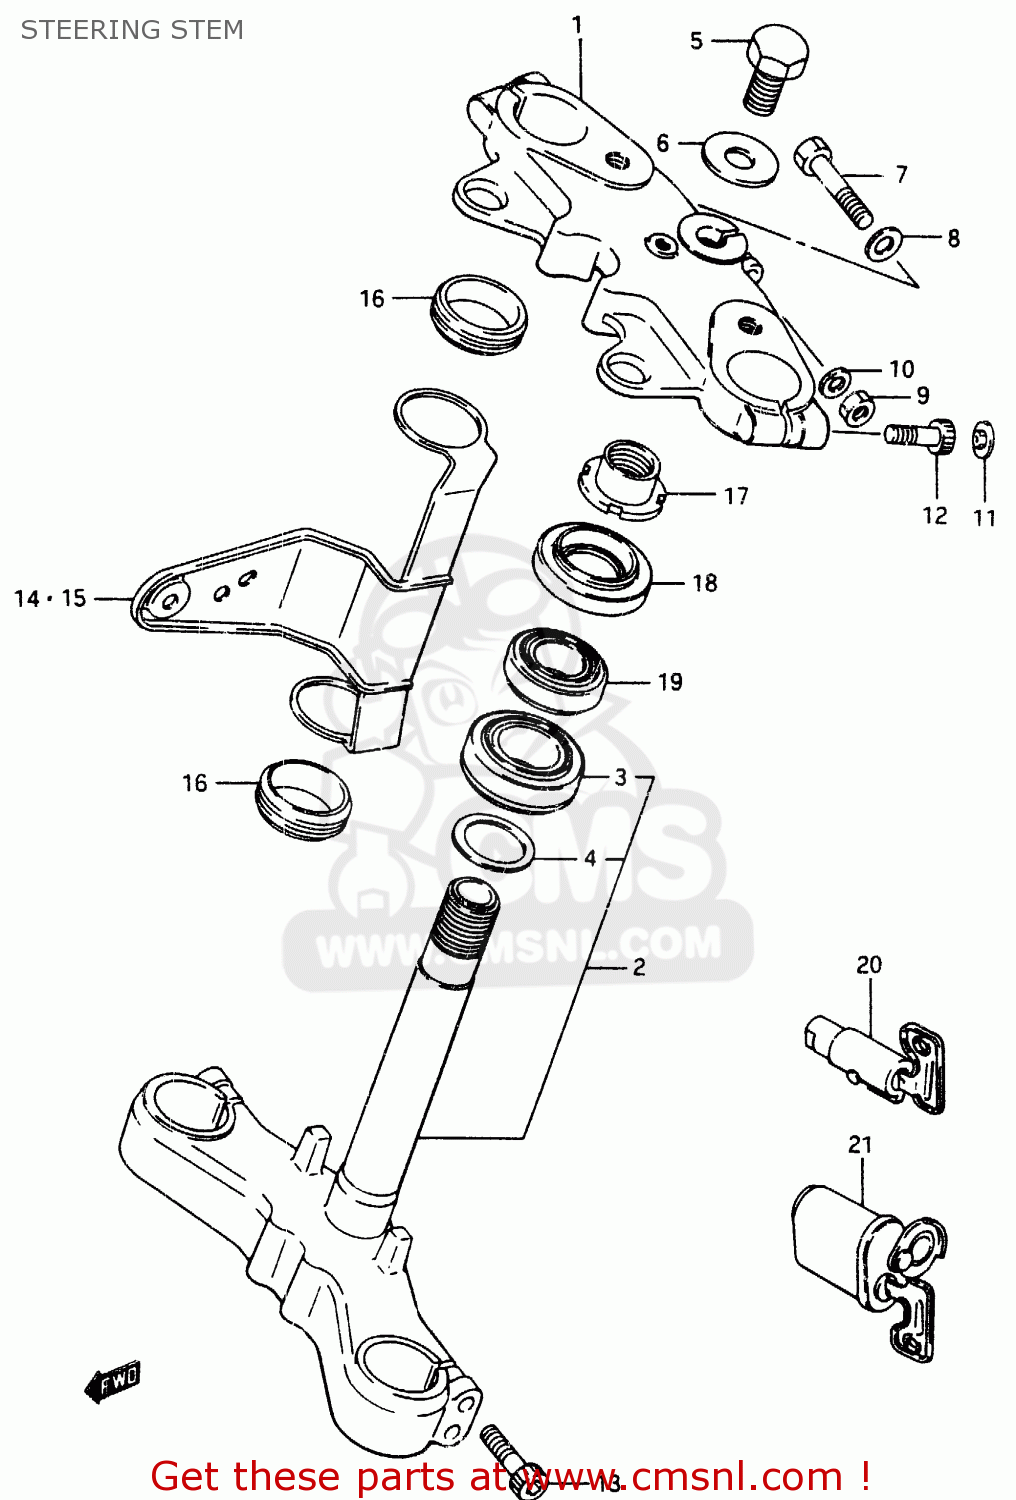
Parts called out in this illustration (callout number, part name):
1	HEAD,STEERING STEM
2	STEM,STEERING
3	BEARING
4	WASHER,THRUST
5	BOLT
6	WASHER,STEM HEAD
7	BOLT
8	WASHER
9	NUT 8MM
10	WASHER,LOCK,8.
11	CAP(OD:20)
12	NUT,STEM HEAD
13	BOLT 8X35
14	BRACKET, HEADLAMP RH (BLACK)
15	BRACKET, HEADLAMP LH (BLACK)
16	CUSHION,HEADLAMP BRACKET
17	NUT,STEERING STEM
18	DUST SEAL,STEERING UPR
19	TAPER,ROLLER BEARING
20	LOCK ASSEMBLY,STEERING (NEI
21	LOCK ASSY, STEERING (NEIMAN TYPE EXECUTE
